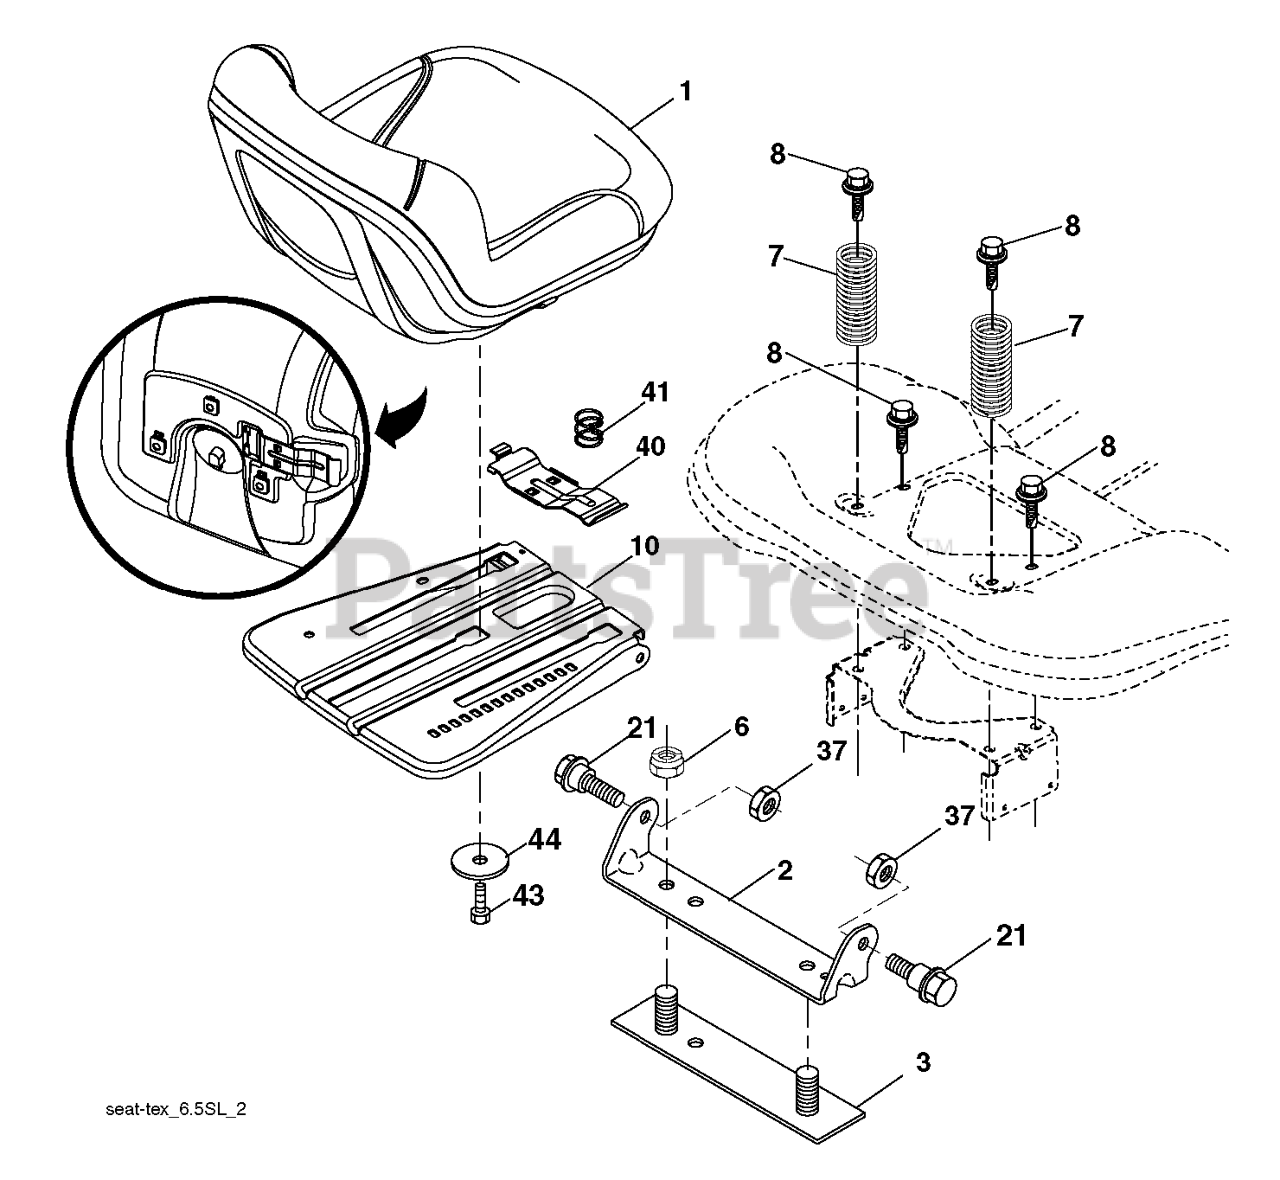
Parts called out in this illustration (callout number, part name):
1	RP SEAT.TH130.GRY.MILSCO.
2	AXLE.CAST.IRON
3	STRAP
6	NUT
7	SPRING COMPRESSION
8	BOLT.5/16-18UNCX3/4 W/SEMS.BLK
10	PAN.ASM.SEAT.3PT
21	BOLT.SHOULDER.5/16-18
37	NUT.71038.31-18.HEX.NYLOCK
40	HANDLE.SLIDE.SEAT.TEX.BLACK
41	SPRING.LATCH.SEAT.TEX
44	WASHER 13/32 X 2-3/8 X 12GA
